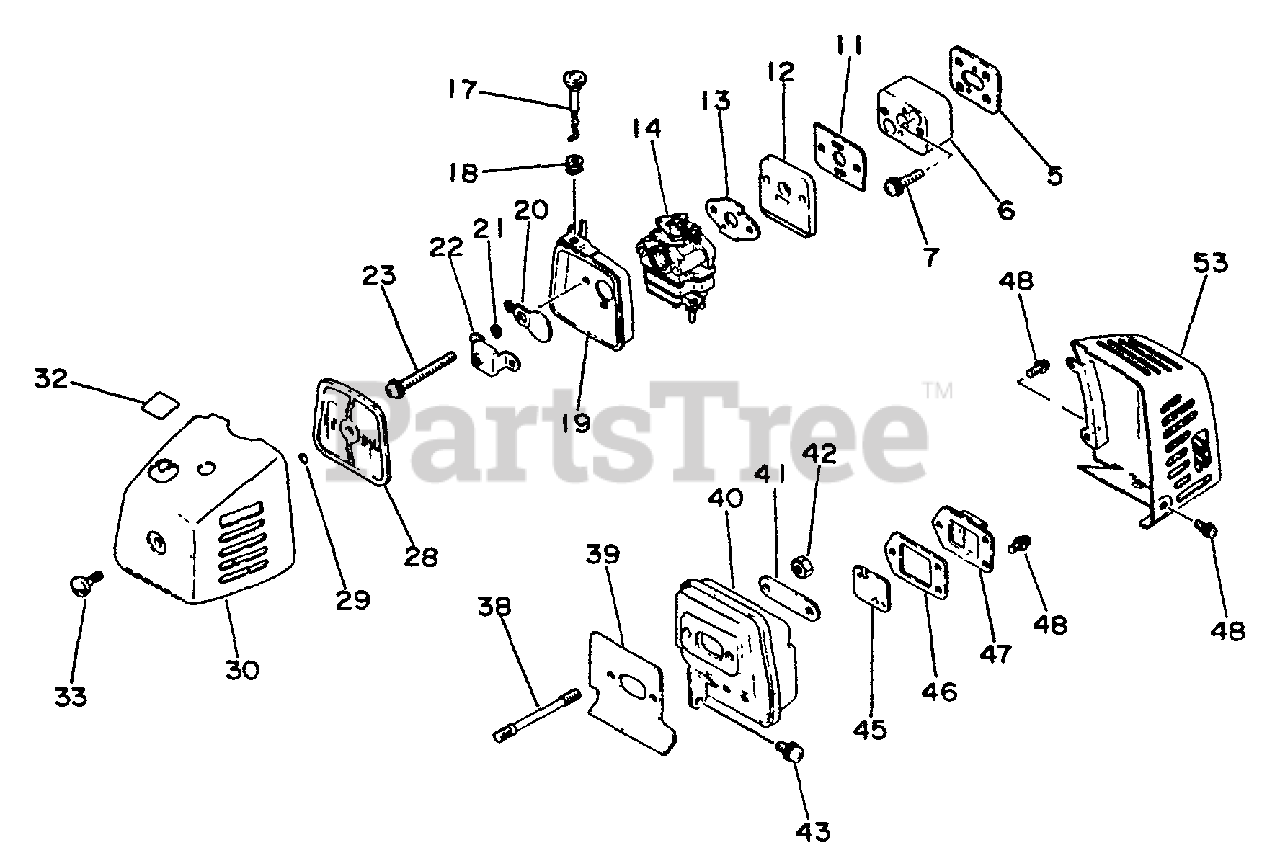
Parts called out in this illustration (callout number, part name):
5	GASKET, INTAKE
6	INSULATOR, INTAKE
7	SCREW - 5X22
11	GASKET, INTAKE
12	PLATE
13	GASKET, INTAKE
14	CARBURETOR
17	ROD, CHOKE
19	CASE, AIR FILTER
20	SHUTTER, CHOKE
21	WASHER - 5
22	PLATE, PREVENT
23	SCREW - 5X50
28	FILTER, AIR
29	O-RING - 4
30	AIR FILTER COVER ASSY
32	LABEL - CHOKE
38	STUD - 5X60
39	GASKET, EXHAUST
40	MUFFLER
42	LOCKNUT - 5
43	SCREW - 5X10
44	GUIDE, EXHAUST
45	SCREEN, SPARK ARRESTOR
46	GASKET, EXHAUST
47	GUIDE, EXHAUST
48	SCREW - 4X8
53	GUIDE, EXHAUST
